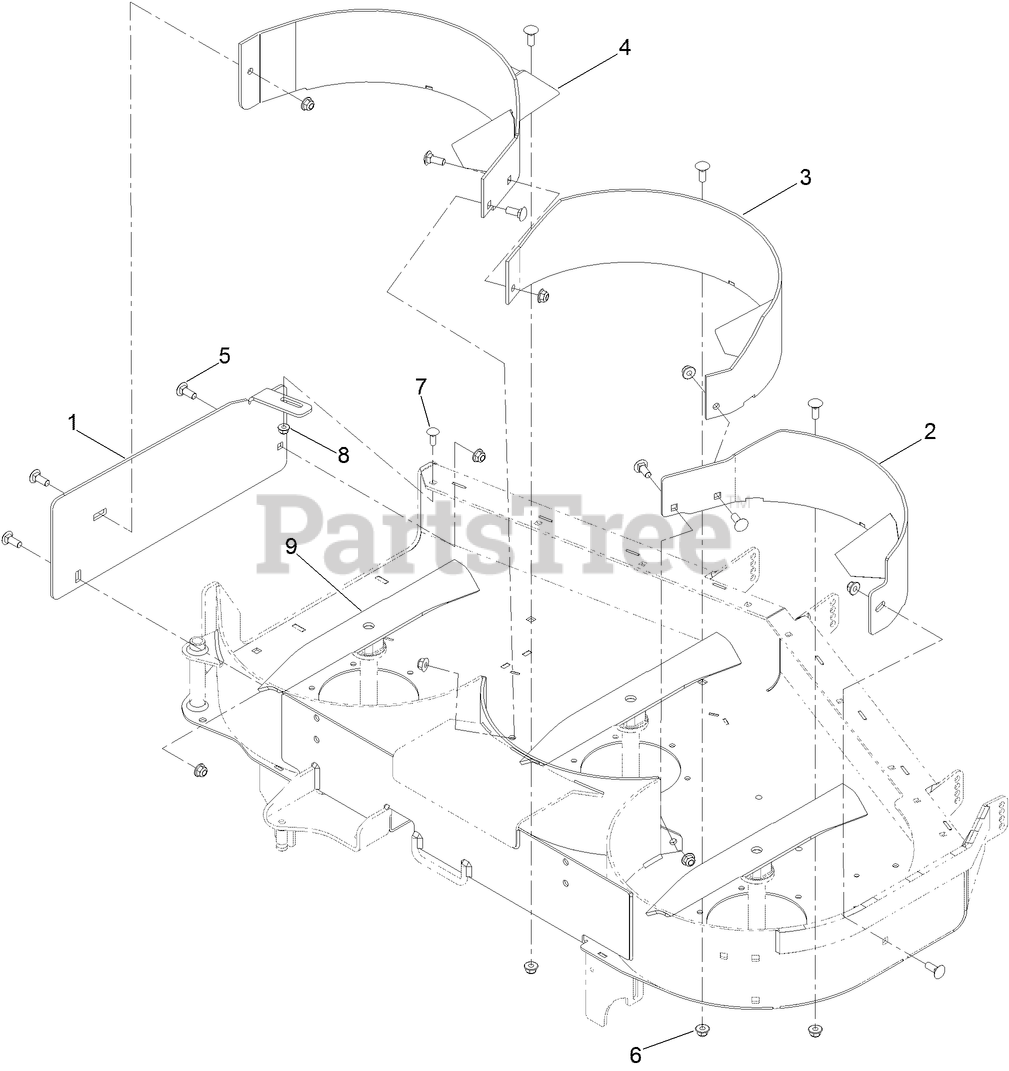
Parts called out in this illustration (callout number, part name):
1	PLATE-COVER, DISCHARGE
2	BAFFLE-LH
3	BAFFLE-CENTER
4	BAFFLE-RH
5	BOLT-CARR
6	NUT-HF, NI
7	SCREW-CARR
8	NUT-HF, NI
9	BLADE-ROTARY, RECYCLING 16.5IN
